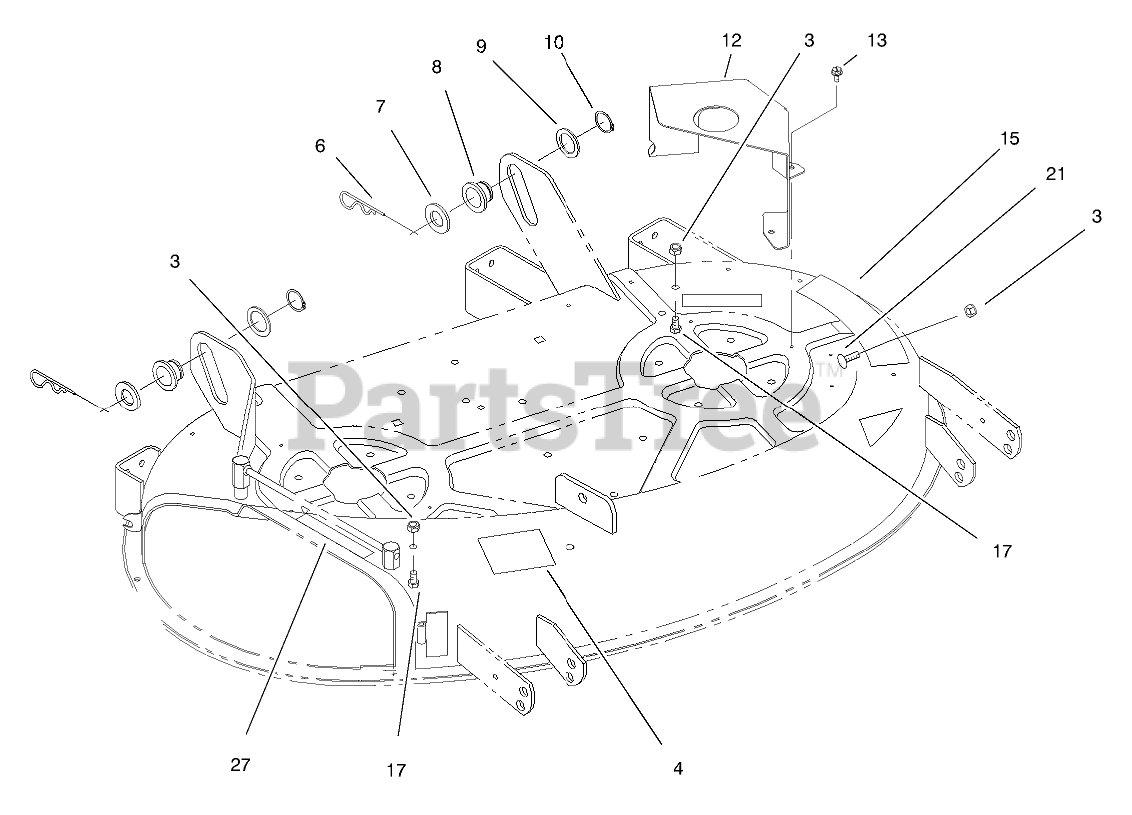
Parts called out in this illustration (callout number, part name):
3	NUT-LOCK, NI
4	DECAL-ROUTING, BELT
6	PIN-HAIR
7	WASHER-FLAT
8	ROLLER-LIFT
9	WASHER
10	RING-RETAINING
12	COVER-BELT
13	SCREW-HWHTF
15	DECAL - DANGER
17	SCREW-HH
21	SCREW-CARR
27	DECAL-DANGER
